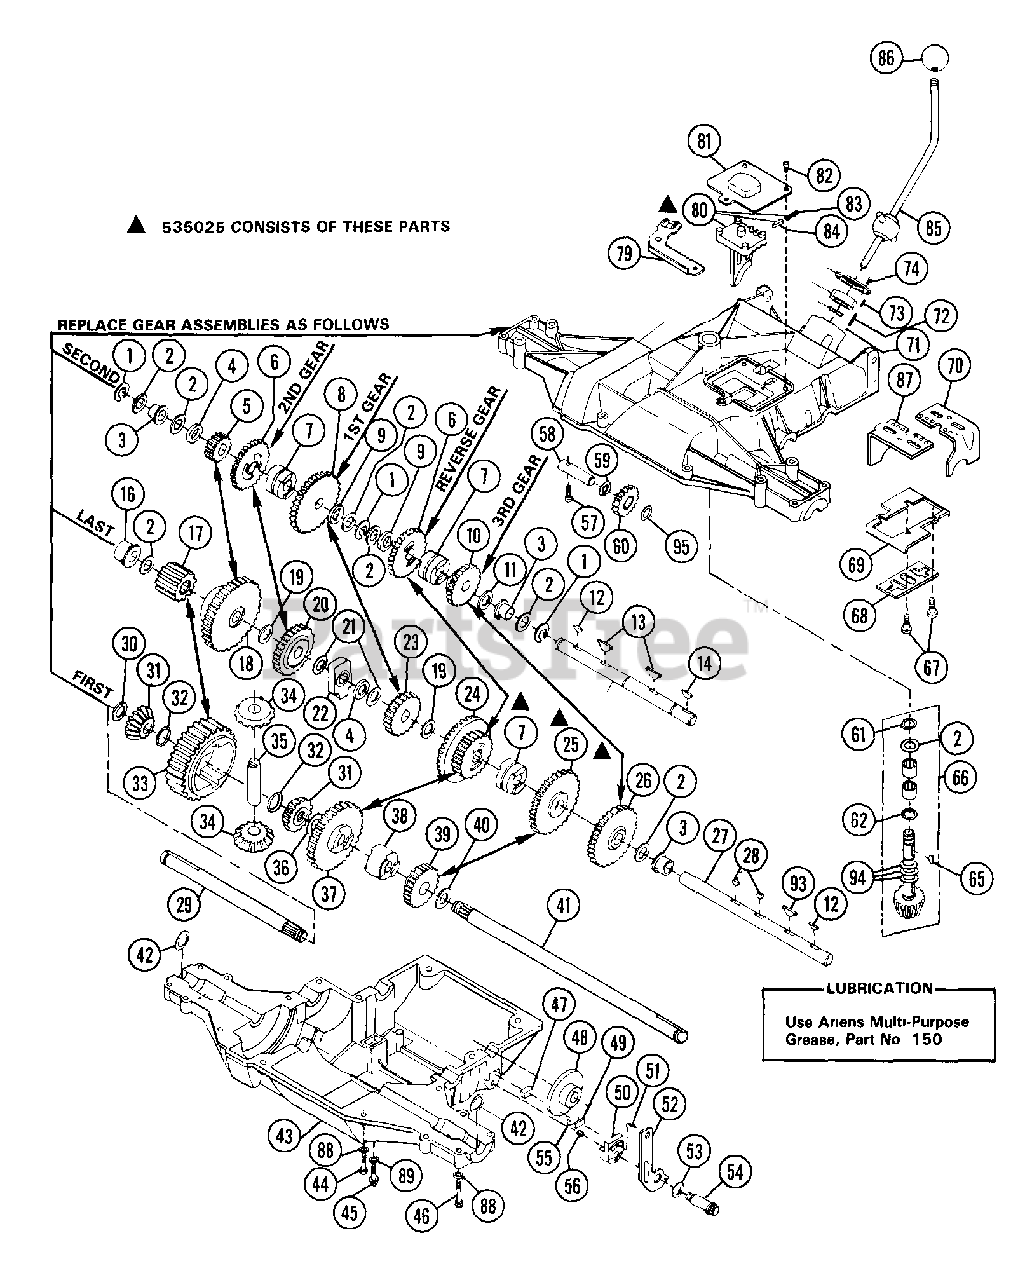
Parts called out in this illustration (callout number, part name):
1	RG-RTNG-EXT .625X.042
2	SHIM KIT
3	FLANGE BEARING
4	SPACER .630X1.000X.110
5	SPUR GEAR 13T
6	SPUR GEAR 25T
7	CLUTCH COLLAR
8	SPUR GEAR 30T
9	SPACER .633X1.00X.260
10	SPUR GEAR 20T
12	KEY-WDRF .125X.500X.203 SAE 3
13	KEY-FTHR FOOTE #3068
14	KEY-WDRF .188X.625X.25 SAE 61
15	INTERMEDIATE SHAFT
16	FLANGE BEARING
17	GEAR ASSY 12T
18	SPUR GEAR 37T
19	WASHER
20	SPUR GEAR 25T
22	SHAFT SUPPORT ASSY
23	SPUR GEAR 20T
24	BEVEL GEAR ASSY
25	SPUR GEAR 33T
26	SPUR GEAR 30T
27	DRIVE SHAFT
28	KEY-WDRF FOOTE #3311
29	L H AXLE
30	SHIM KIT
31	SPLINED MITER GEAR 15T
32	RG-RTNG-EXT .625X.035
33	SPUR GEAR 32T
34	MITER GEAR 15T
35	CROSS SHAFT
36	WSHR-HDND-THRST .758X1.23X.031
37	SPUR GEAR 35T
38	GEAR LOCK
39	SPUR GEAR 22T
40	WSHR-FL-STL .760X1.250X.060 PL
41	R H AXLE
42	SEAL J.B.FOOTE #5130
43	LOWER HOUSING
44	BLT-HEX .25-20X1.00 GR2
45	SCR-MCH 12-24X.62 HEXWH
46	BLT-HEX .25-20X1.25 PL GR5
47	BRAKE JAW FRICTION PUCK
48	BRAKE DISC
49	SPACER - FLAT .045 THICK
50	BRAKE JAW ASSY
51	SCR-SET 8-32 FOOTE 1606
52	ACTUATING LEVER ASSY
53	SHIM KIT
54	SHOULDER BOLT
55	FRICTION PAD
56	SG-COMP J.B. FOOTE
57	SCR-MCH 10-24X1.00 HEX PL
58	IDLER SHAFT
59	WSHR-FL-STL .505X1.000X.020
60	IDLER GEAR ASSY
61	RG-RTNG-EXT .625X.035
62	O-RING .612X.805X.102
65	KEY-WDRF .188X.75X.313 SAE 9
66	INPUT SHAFT ASSY KIT
67	BLT-HEX .25-28X.75 PL GR5
68	LOCK-OUT PLATE
69	FORK PLATE SUPPORT
70	SHIFTER FORK
71	DETENT BALL
72	SG-COMP ??X??X?? FOOTE
73	SCR-SET .25-20X.38 SKHCUP OH
74	SCR-MCH 10-24X.50 SLTR PL
75	WAVE WASHER .760X1.062X.105FH
76	NYLON INSERT
77	NYLON COVER
78	UPPER HOUSING
79	HI-LO SHIFT LEVER
80	SELECTOR FORK KIT
81	HI-LO COVER PLATE
82	SCR-MCH 8-32X.50 SLTR PL
83	SG-COMP .035X.186X.702
84	DETENT PIN
85	SHIFT LEVER ASSY
86	SHIFT BALL
87	SHIFTER FORK
88	WSHR-LK .250X.077 HVY PL
89	WSHR-LK-EXT 12X.025 PL
93	KEY-FTHR FOOTE #3068
94	SHIM KIT
95	WASHER
96	WSHR-FL-STL .633X1.000X.041
